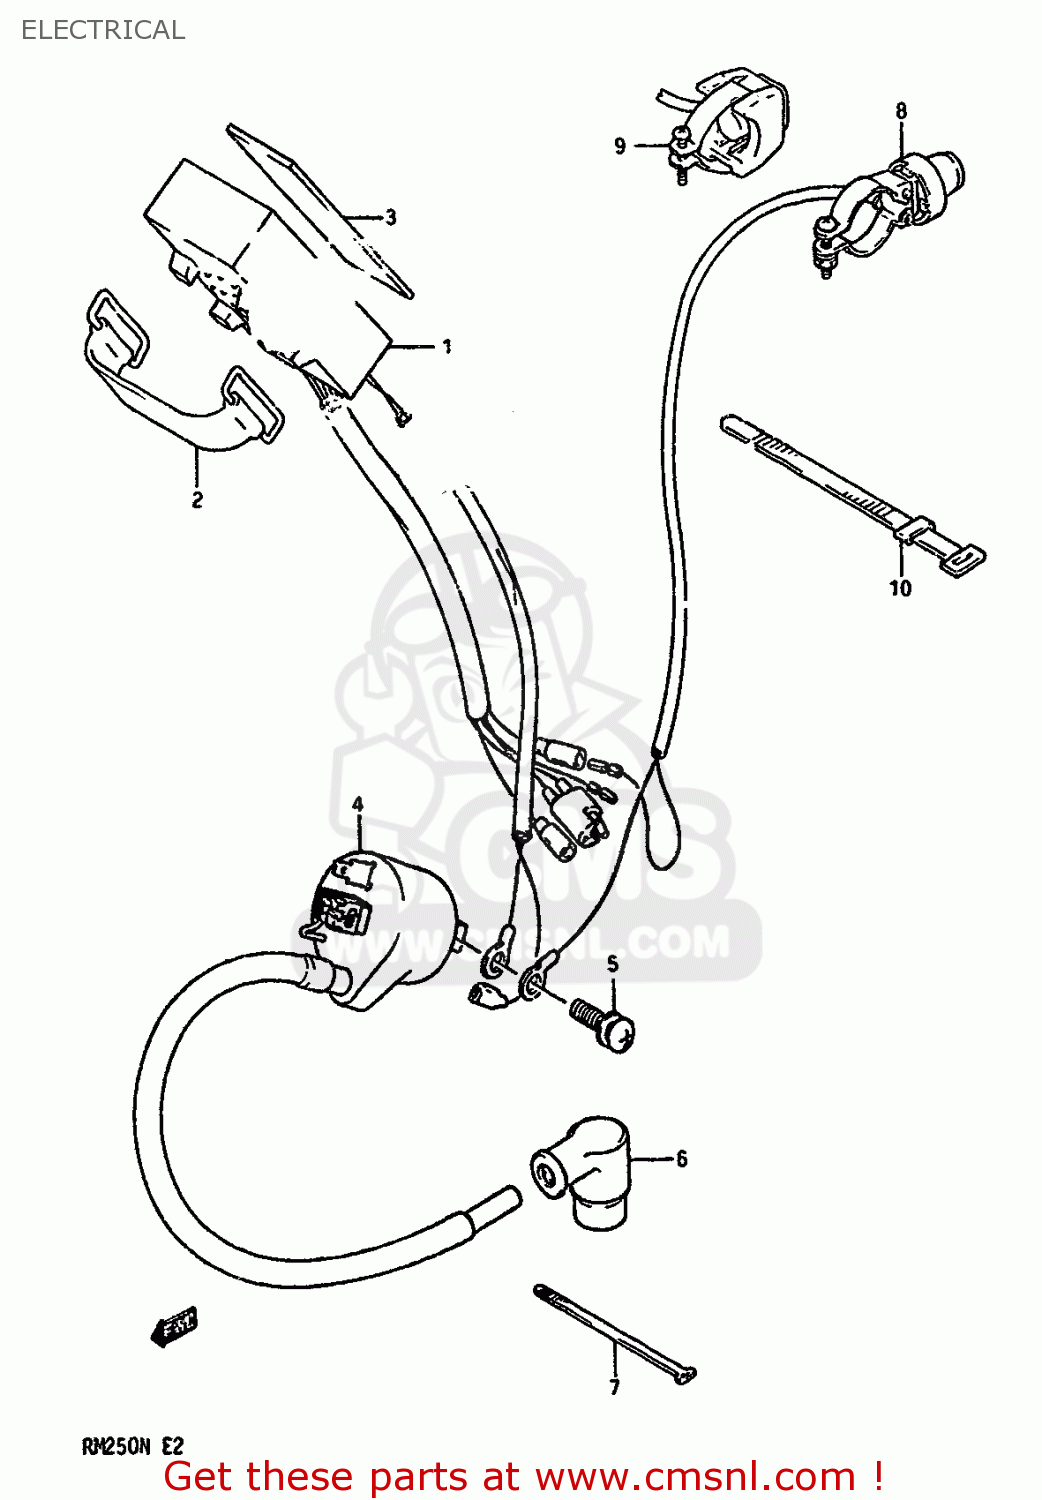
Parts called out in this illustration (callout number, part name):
1	CDI UNIT
2	BAND
3	PROTECTOR(170X95X3.0)
4	COIL ASSEMBLY,IGNITION
5	SCREW
6	CAP,SPARK PLUG
7	CLAMP
8	SWITCH ASSEMBLY
9	SWITCH ASSEMBLY
10	CLAMP(L:120)
